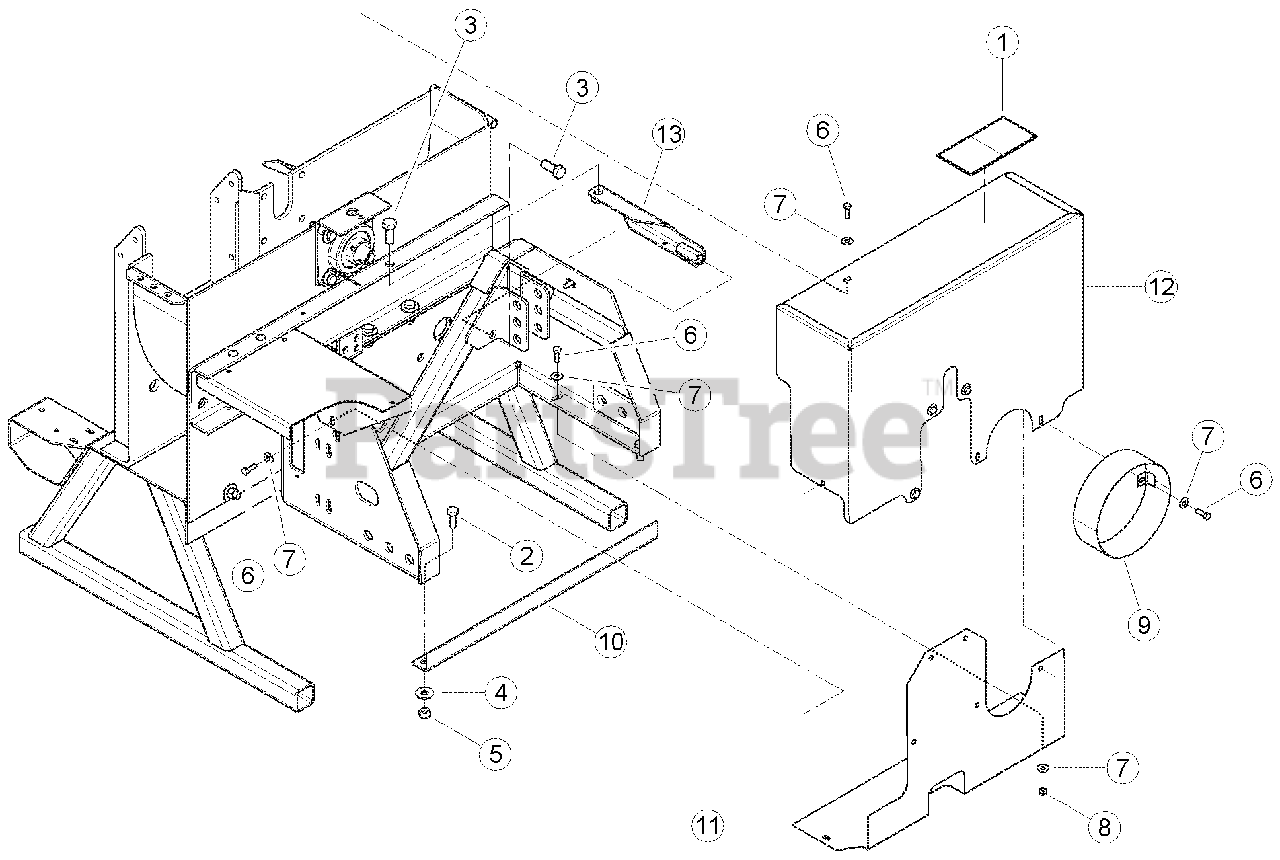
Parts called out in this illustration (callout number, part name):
1	DECAL, PTO DANGER ISO
2	BOLT, 1/2 X 1-1/4 HEX HD GR5 NC ZP
3	BOLT, 5/8 X 1-1/2 HEX HD GR5 ZP
4	WASHER, 1/2 FLAT ZP
5	NUT, 1/2 CENTERLOCK GRB ZP
6	BOLT, 5/16 X 1 HEX HD GR5 NC ZP
7	WASHER, 5/16 FLAT ZP
8	NUT, 5/16 NE NYLOCK ZP
9	WELDMENT, JOINT SHIELD
10	BRACE, 3 POINT BOTTOM
11	WELDMENT, GUARD PTO LOWER BELT
12	WELDMENT, GUARD PTO UPPER BELT
13	WELDMENT, BRACE PTO 3-POINT
